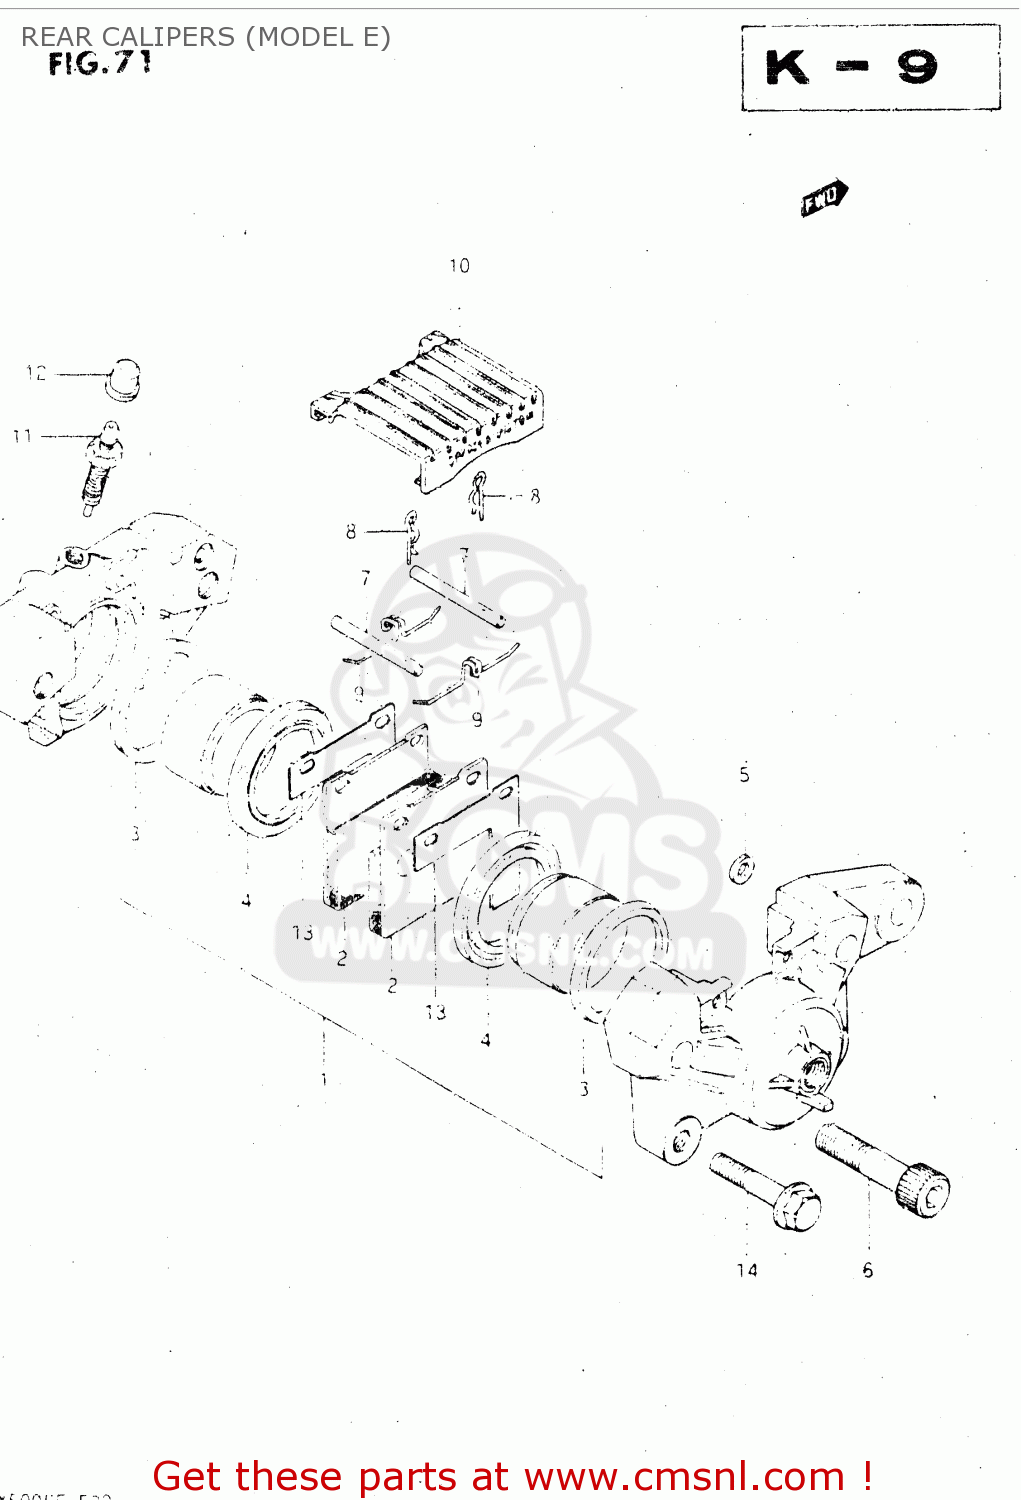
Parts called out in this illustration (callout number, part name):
1	PISTON SET
2	PAD
3	SEAL,PISTON
4	BOOT
5	SEAL,JOINT
6	BOLT,CALIPER HOUSING
7	PIN,PAD
8	CLIP,PAD PIN
9	SPRING
10	COVER,CALIPER
11	BLEEDER
12	CAP,BREATHER
13	SHIM
14	BOLT
